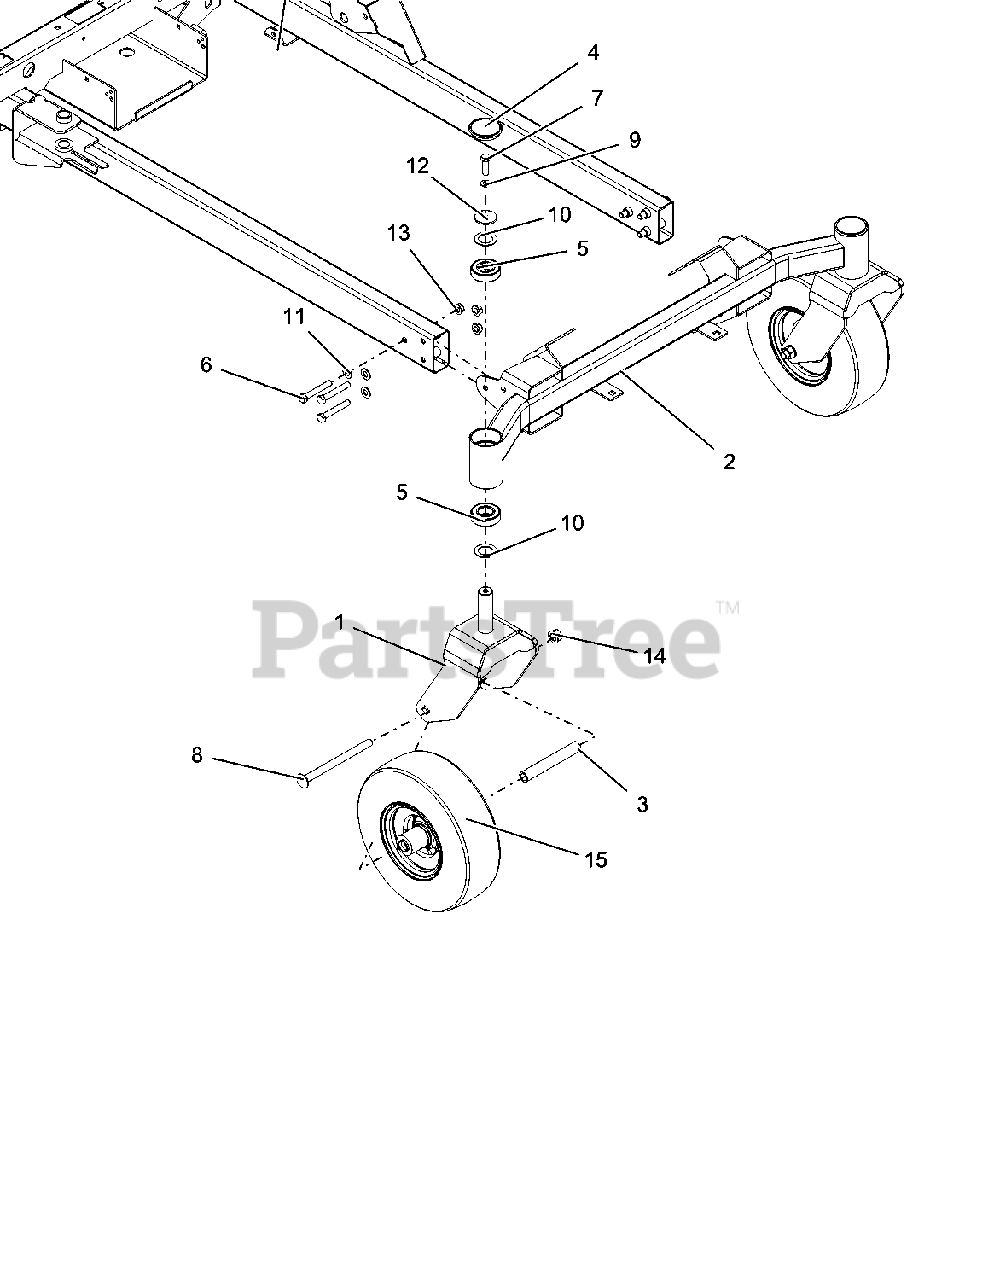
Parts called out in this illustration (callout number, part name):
1	WLDMT, CASTER FORK (RED)
2	WLDMT, AXLE FRONT
3	SPCR, ROLLED WHEEL
4	CAP, DUST
5	BRG-BALL 1.00X2.00X.56
6	BLT-HEX .38-16X2.50 GR8 YWZC
7	BLT-HEX .38-16X1.25 GR5 YWZC
8	BLT-RDHDSQNK .50-13X6.50 G5 Y
9	WSHR-LK .38X.094 REG YWZC
10	WSHR, HRD THRS 1.007X1.542X.062
11	WSHR-HDND .406X.812X.075
12	WSHR-FL-STL .380X1.50X.125 YWZC
13	NUT, LK-TOP-FLG .38-16 GRG YWZC
14	NUT, LK-TOP-FLG .50-13 YWZC
15	TIRE/WHEEL, 11 X 4-5
